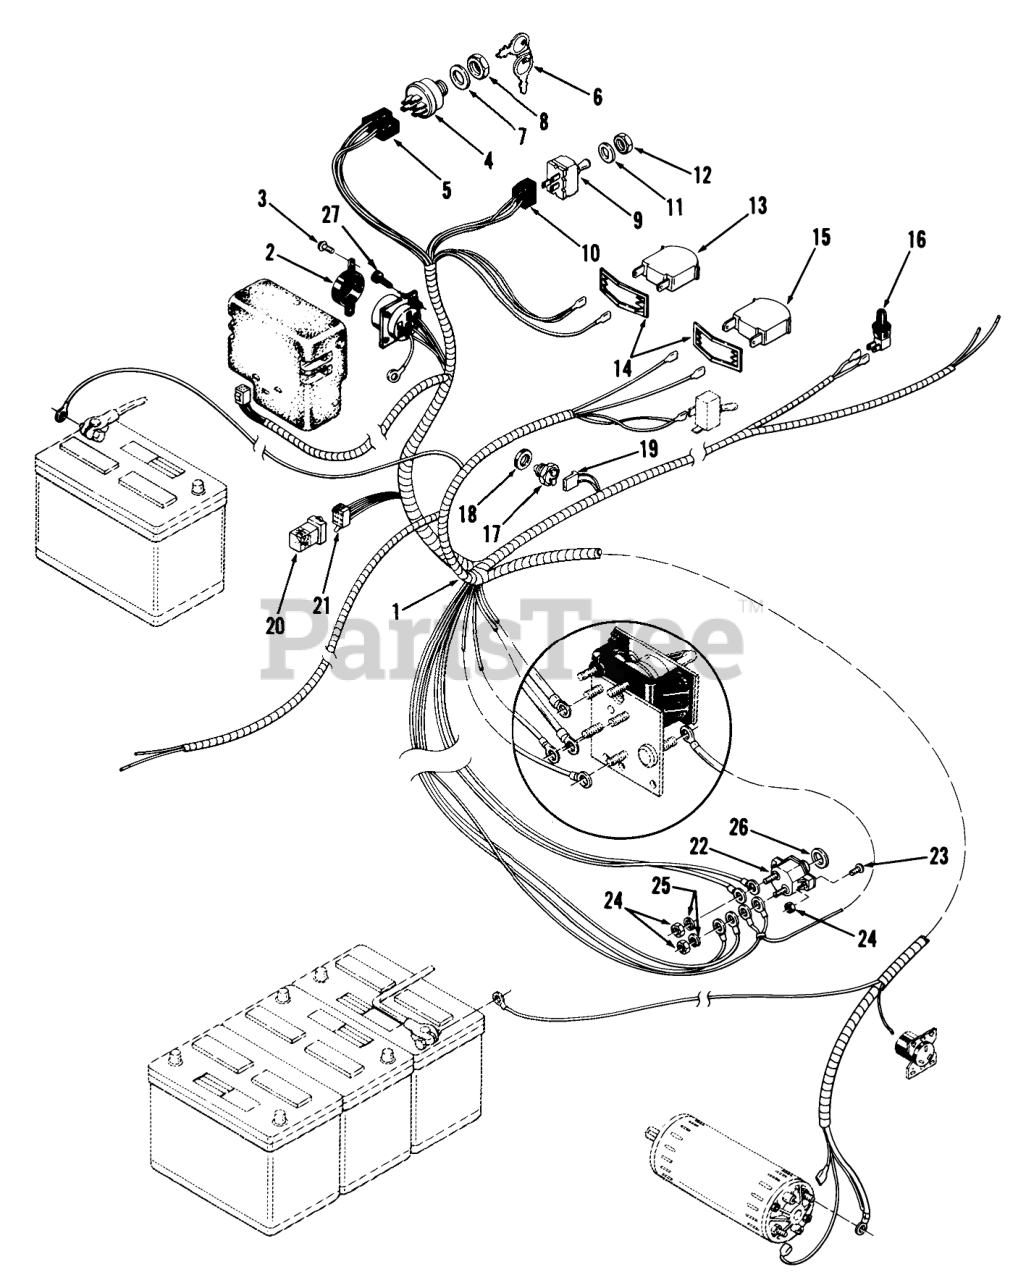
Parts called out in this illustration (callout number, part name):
1	Wiring Harness-Control Circuit
2	Charger Receptacle Cover
3	Plate Screws
4	SWITCH-IGNITION
5	CONNECTOR-5 WAY-SERV
6	Key-EL
7	LOCKWASHER
9	PTO Switch
10	3-CONTACT CONNECTOR
11	Lockwasher 1/2 Int. Tooth
12	Nut, 1/2-27
13	Fuel Level Meter
15	Battery Balance Meter
16	SWITCH-SEAT
17	SWITCH-INTERLOK CLUT
18	NUT-SPECIAL 9/16-18
19	CONNECTOR BODY
20	Resistor Module
21	Socket Housing
22	Circuit Breaker
23	Screw #10-32 X 5/8 Sems
24	Nut
25	Lockwasher
26	Neoprene Washer 5/16
27	S.T. Screw #8-32 x 1/2
